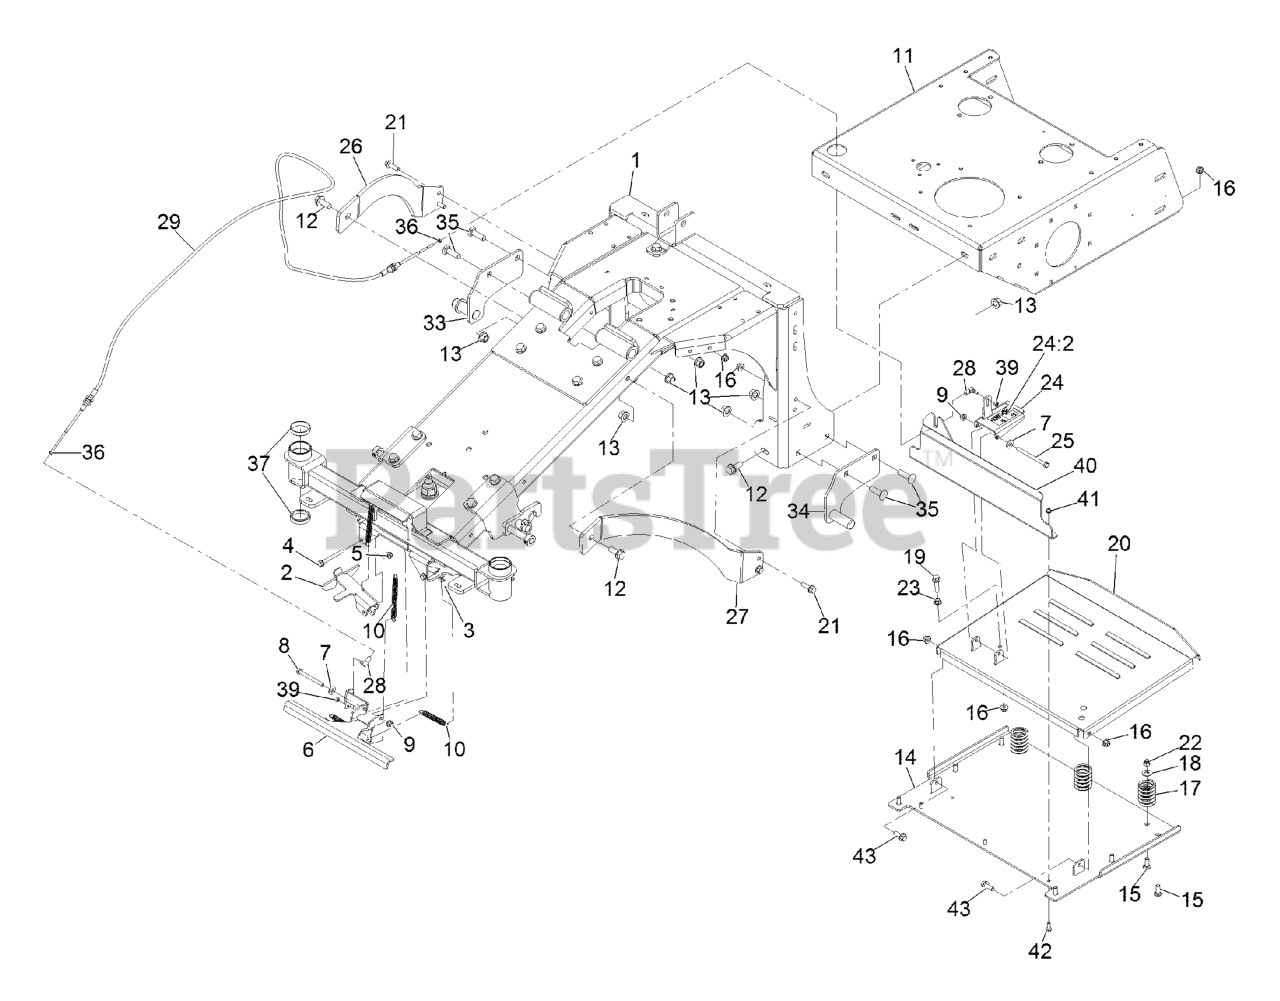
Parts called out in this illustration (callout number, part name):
1	Front Frame ASM
2	WING-CASTER RH
3	WING-CASTER LH
4	SCREW-HHF
5	Nut-Hex Flange
6	ARM-BODY, LCS
7	Washer-Flat
8	SCREW-HH
9	NUT-HF, NI
10	SPRING-EXTENSION
11	REAR FRAME ASM
12	SCREW-HHF
13	Nut-Lock 1/2-13
14	FRAME BASE
15	SCREW-CARR
16	NUT-HF, NI
17	SPRING-COMPRESSION
18	Washer-Flat
19	SCREW-HHF
20	WLD, FOOTPLATE, AE
21	SCREW-HHF
22	NUT-LOCK, NI
23	NUT-HEX FLANGE
24	PEDAL-FOOT
24:2	Decal-Lock, Caster
25	SCREW-HH
26	BRACE-FRAME, RH
27	BRACE-FRAME, LH
28	BALL JOINT-SS
29	ZPLUG LOCKING CASTER CABL
33	PIVOT-BRAKE, RH
34	PIVOT-BRAKE, LH
35	SCREW-CARR
36	Nut,Hex Jam Mch Scr,10-32,Sst
37	BEARING-CUP, TAPERED
39	Nut,NYL Lock,#10-32,ST/ST 18-8
40	SHIELD-HEAT, MUFFLER
42	SCREW-HHF
43	SCREW-HHF 3/8-16 X 1
